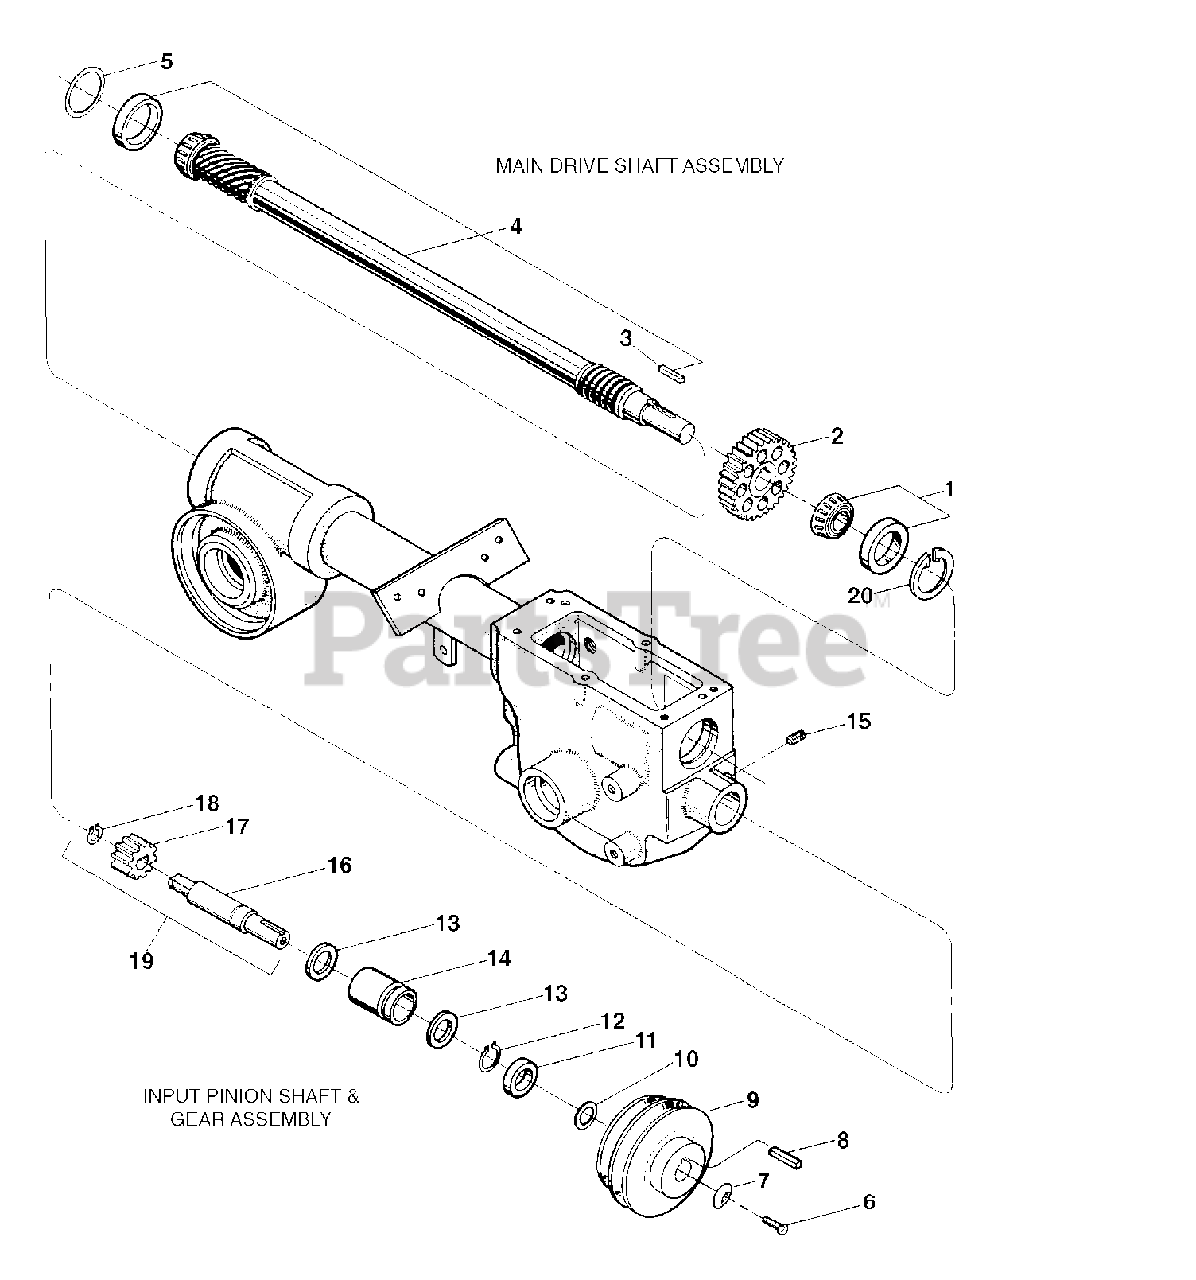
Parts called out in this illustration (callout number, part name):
1	Bearing, Tapered Roller with Race
2	Spur Gear
3	Key, 3/16 sq. x 1
4	Main Drive Shaft
5	Shim, Rear Bearing Cap, .010" thick
5	Shim, same as above, but .030" thick
5	Shim, same as above, but .005" thick
6	Hex Hd. Screw, 5/16-24 x 1-1/8
7	Washer, Disc Spring (concave surface faces pulley)
8	Key, 3/16 sq. x 1-1/2
9	Transmission Drive Pulley
10	Support Washer
11	Oil Seal, Input Pinion Shaft
12	Retaining Ring (external)
13	Thrust Washer
14	Bushing
15	Set Screw, 5/16-18 x 3/8
16	Input Pinion (steel shaft)
17	Input Pinion Gear
18	Retaining Ring (external)
19	Pinion Assy.
20	Retaining Ring (internal)
